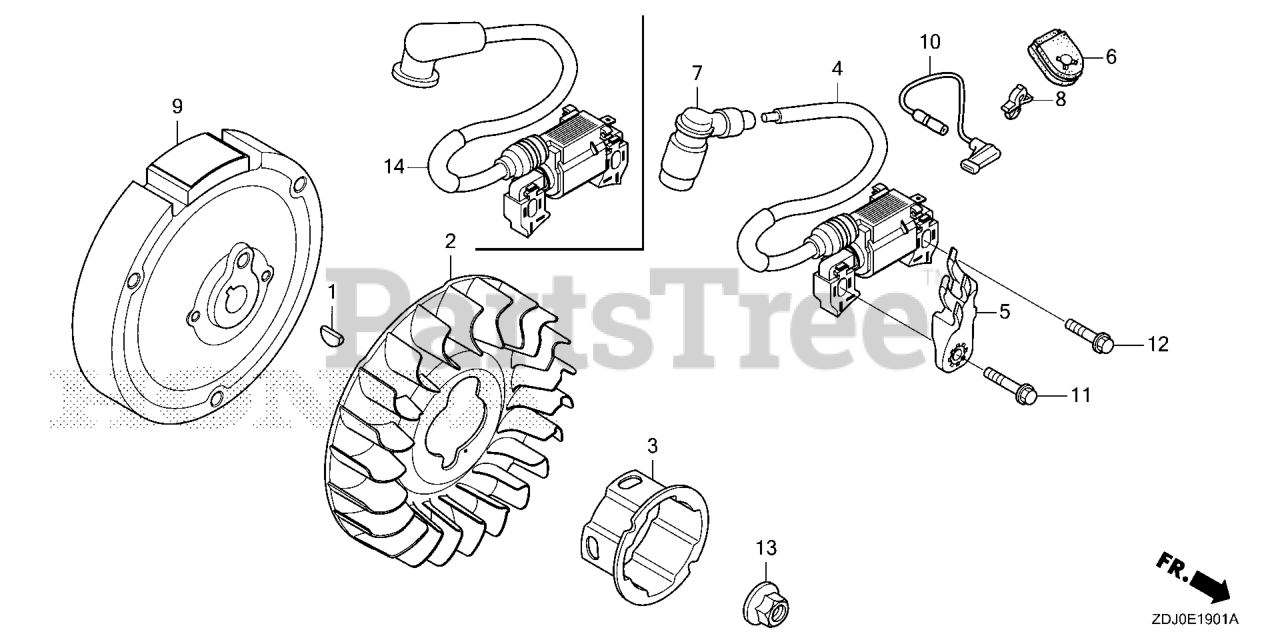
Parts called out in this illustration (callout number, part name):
1	KEY, SPECIAL WOODRUFF (25X18)
2	FAN, COOLING
3	PULLEY, STARTER
5	CLAMP, IGNITION WIRE
6	GROMMET, WIRE
11	BOLT (6X30) (CT200)
12	BOLT, FLANGE (6X25) Use up to Engine SN 2056819.
13	NUT, SPECIAL (14MM)
14	COIL ASSY., IGNITION
